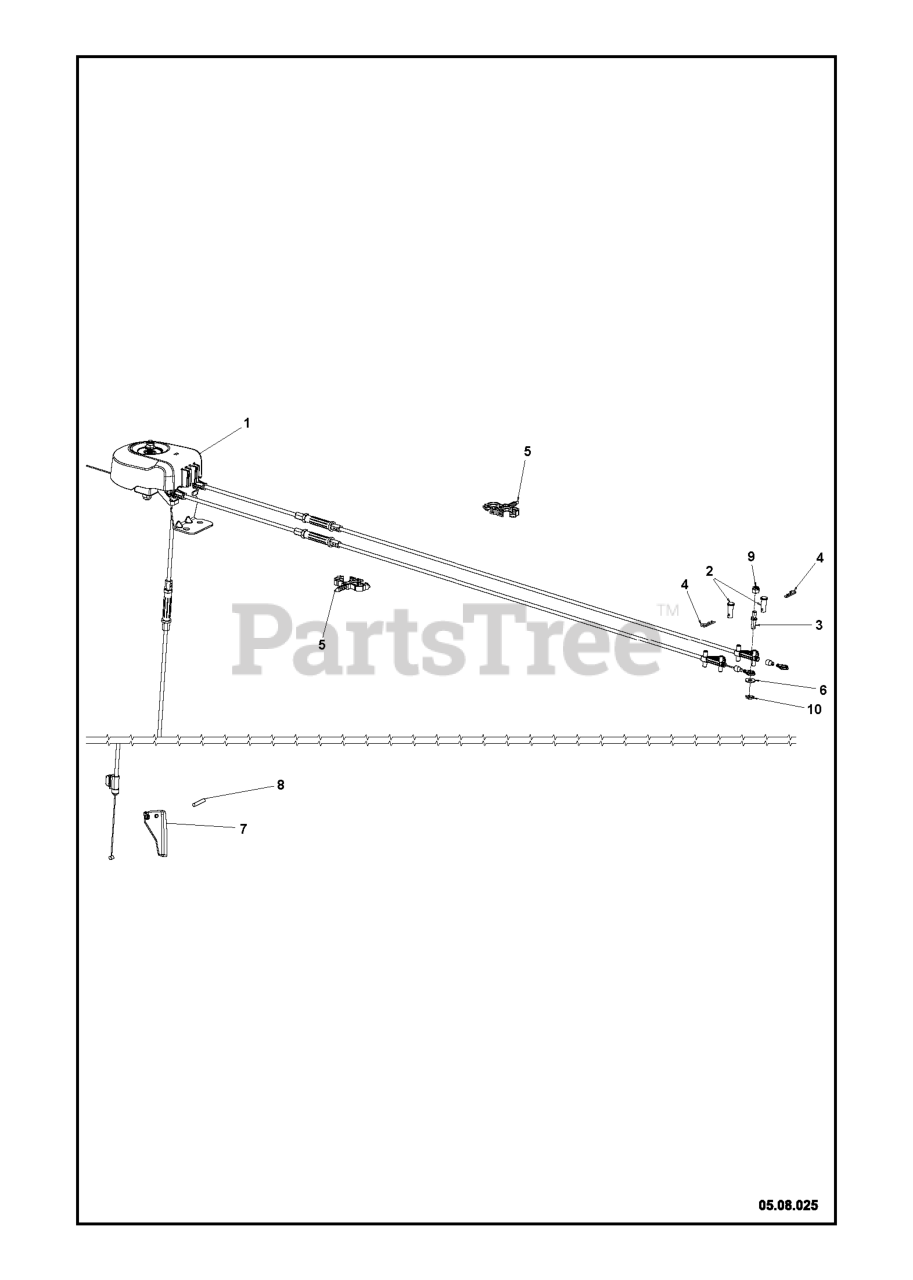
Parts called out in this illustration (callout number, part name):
1	CABLE CHUTE ROTATOR ASM LOCKIN
2	PIN CLEVIS 5/16X.875
4	HAIRPIN.SOFT.ZINC.059X1.125
5	CLIP.CONDUIT.DOUBLE LOOP
6	WASHER FLAT_.250 X .625 X .06
8	PIN.ROLL.3/16 X 1"
9	NUT HEXAGON 1/4-20 ST ZPB
